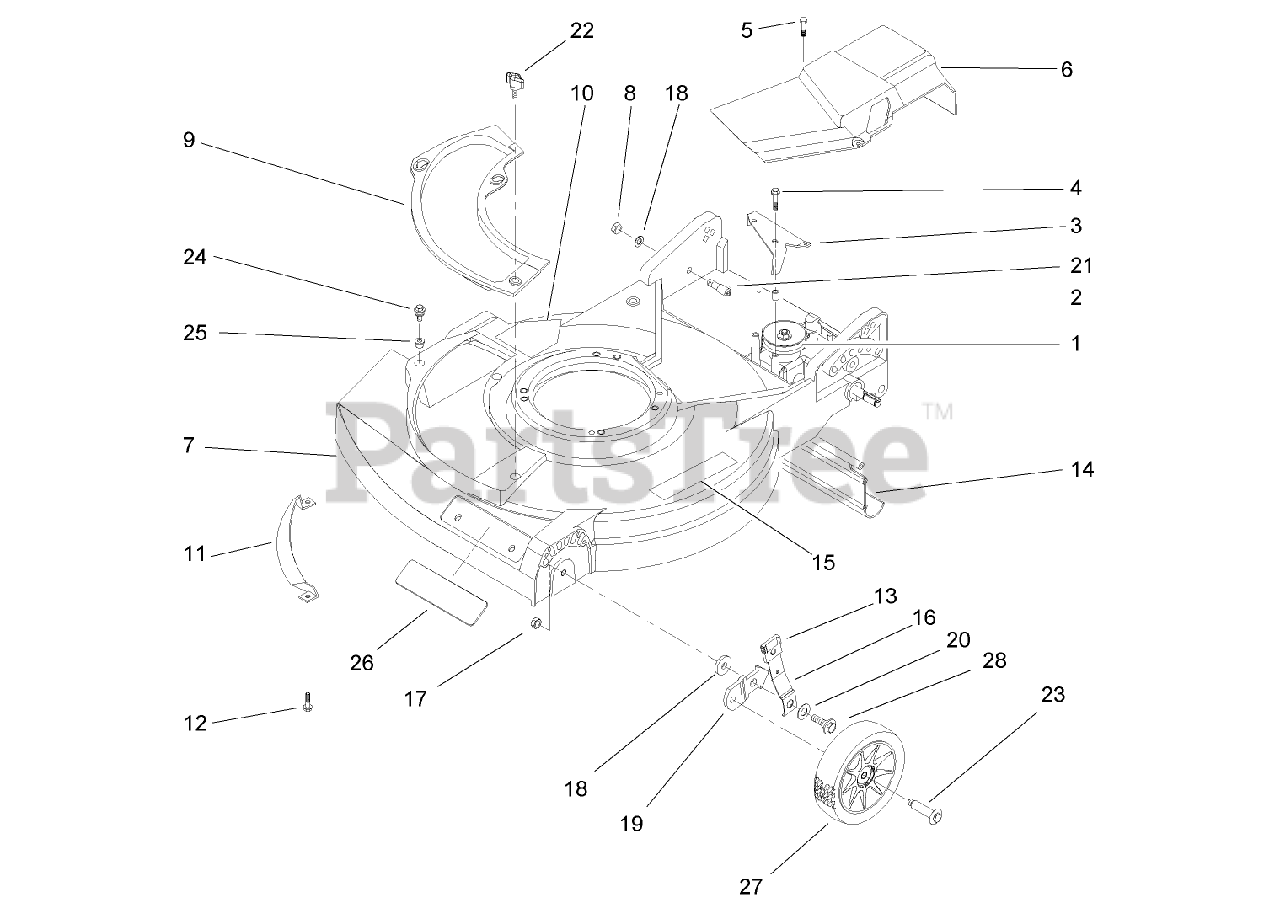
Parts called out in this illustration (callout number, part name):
1	GEAR CASE ASM
2	SPACER
3	BRACKET-ACTUATOR
4	SCREW-HWH
5	SCREW-HWH
6	COVER-DRIVE
7	HOUSING ASM
9	PLATE-OPENING, CHUTE
10	DECAL-DANGER
11	BAR-TOE
12	SCREW-HWH
13	KNOB-LEVER, HEIGHT ADJUSTMENT
14	SHIELD-TRAILING
15	DECAL-WARNING
16	FRONT SPRING ARM ASM
17	NUT-LOCK, NI
18	WASHER
19	BRACKET-HEIGHT ADJUSTMENT, WHEEL
20	WASHER-BELLEVILLE
21	BOLT-SHOULDER
24	SCREW-SEMS
25	NUT-CLIP
27	WHEEL AND TIRE ASM
28	BOLT-SHOULDER
